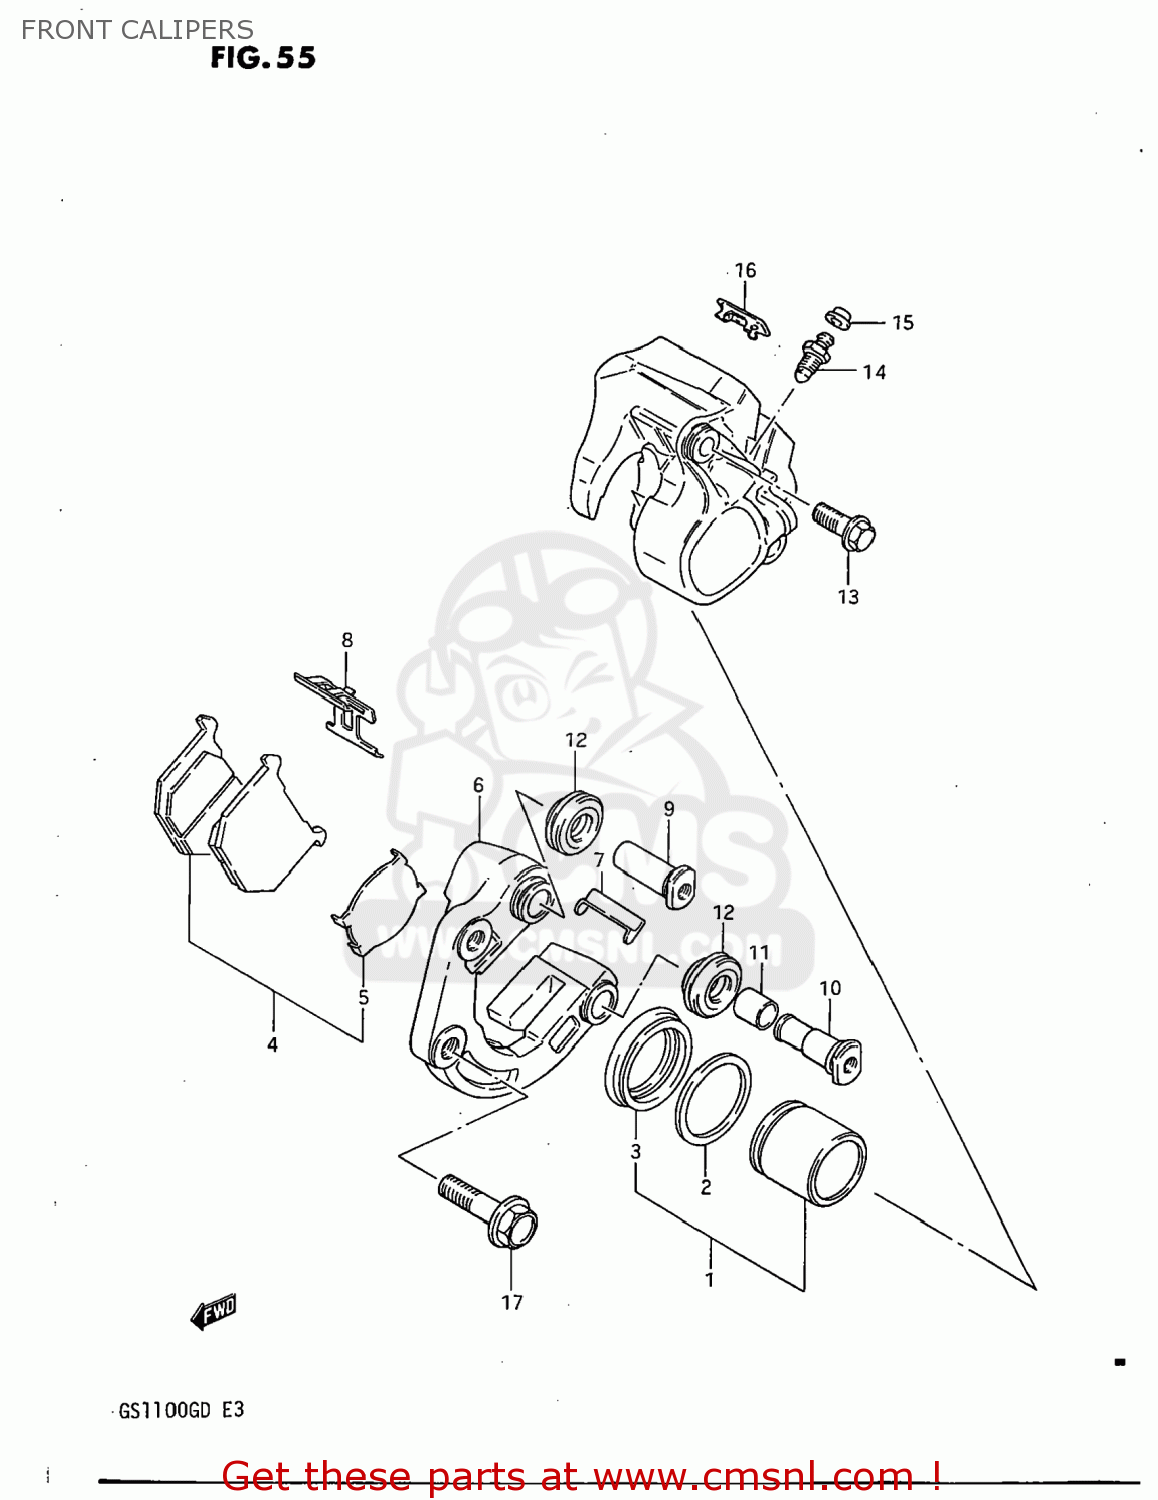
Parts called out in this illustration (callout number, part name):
1	PISTON SET
2	SEAL,PISTON
3	BOOT,PISTON
4	PAD SET,BRAKE (MCA)
5	SHIM,PAD
6	CARRIER,CALIPER,LEFT
7	GUIDE,PAD
8	SPRING,PAD
9	AXLE NO.1
10	AXLE NO.2
11	BUSH,AXLE
12	BOOT,AXLE
13	BOLT
14	BLEEDER
15	CAP,BREATHER
16	COVER
17	BOLT(10X37)
